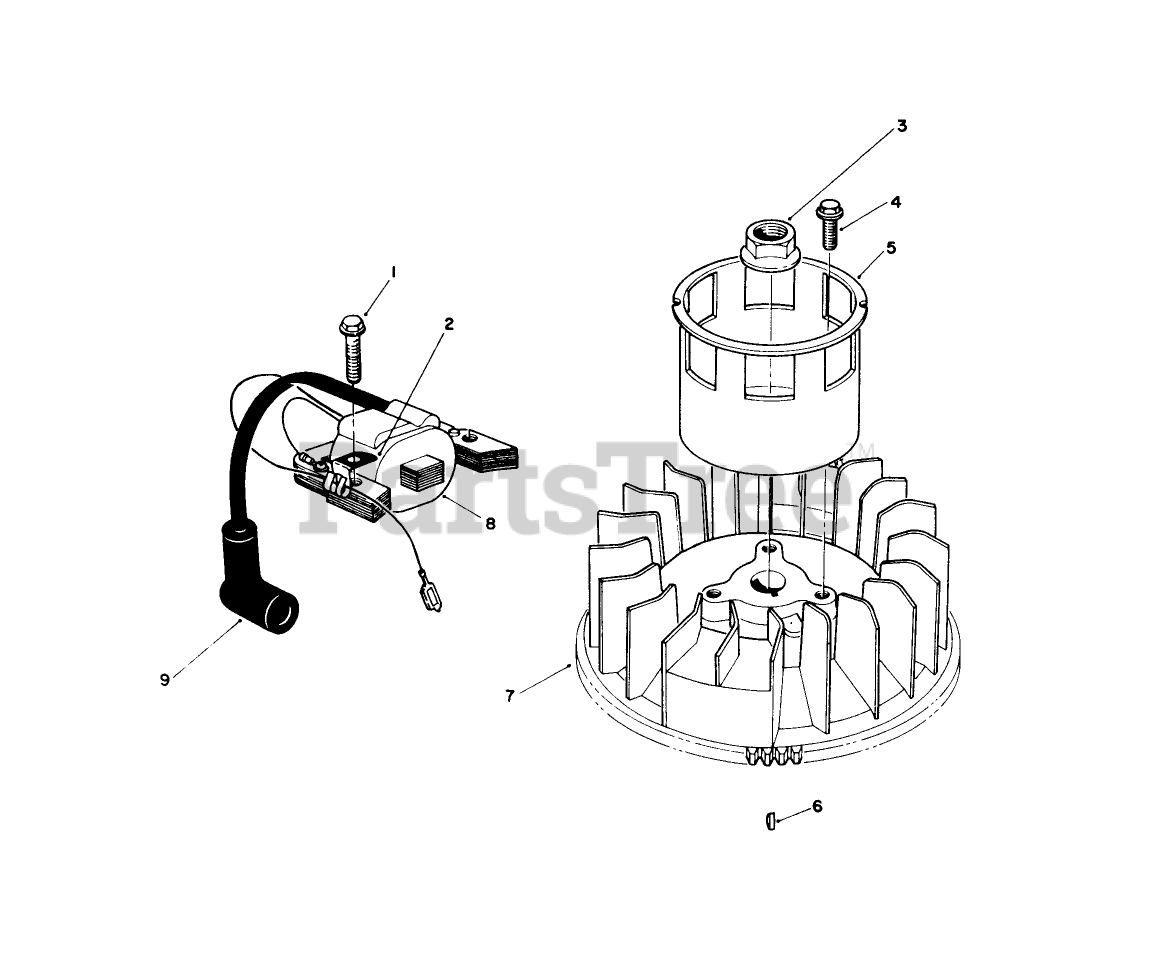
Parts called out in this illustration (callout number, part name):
2	CLAMP
7	FLYWHEEL
8	COIL ASM
9	COVER
